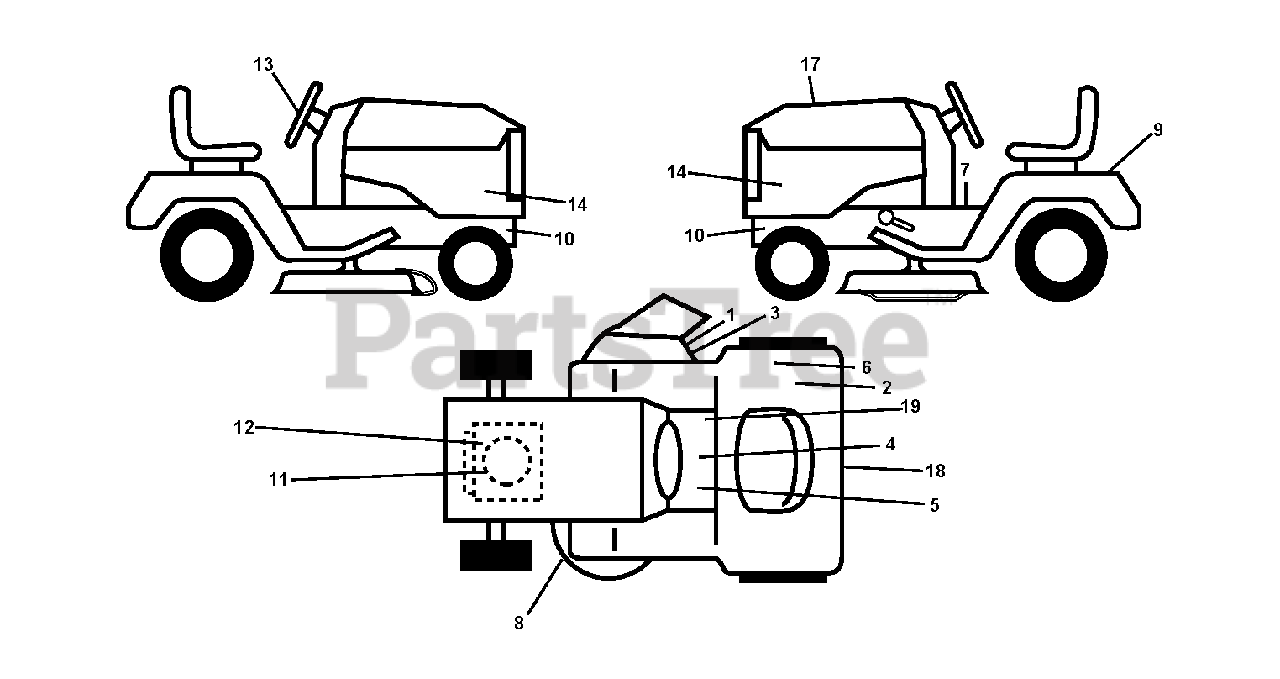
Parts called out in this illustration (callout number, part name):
1	DECAL.INTERNATIONL.CUTFINGER
3	DECAL, DEFLECT WARNING
4	DECAL PARK BRAKE
6	DECAL.80 DBA.AUSTRALIA
8	DECAL V BELT SCHEMATIC
9	DECAL BTRY SYMBOLS
